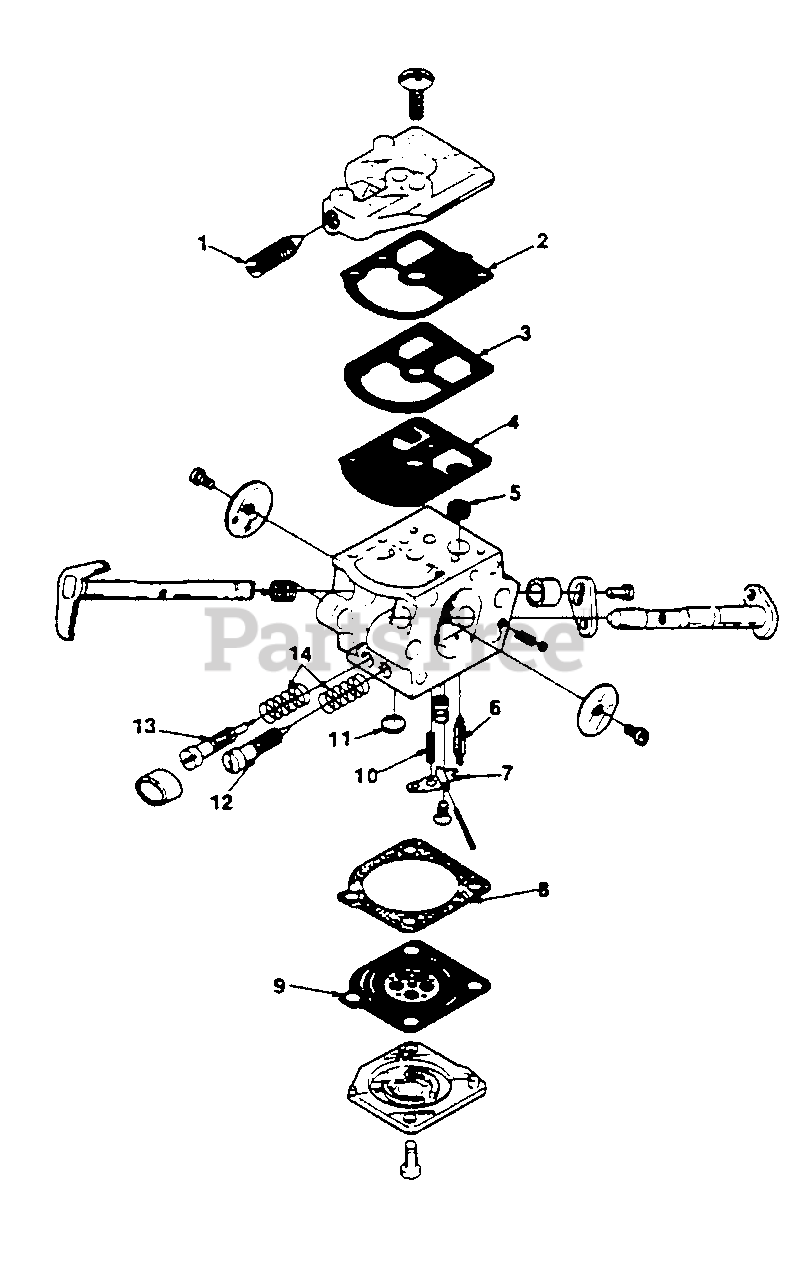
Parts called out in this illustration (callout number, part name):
1	Repair Kit
2	Repair Kit
3	Repair Kit
4	Repair Kit
5	Repair Kit
6	Repair Kit
7	Repair Kit
8	Repair Kit
9	Repair Kit
10	Repair Kit
11	Repair Kit
12	Repair Kit
13	Repair Kit
14	Repair Kit
